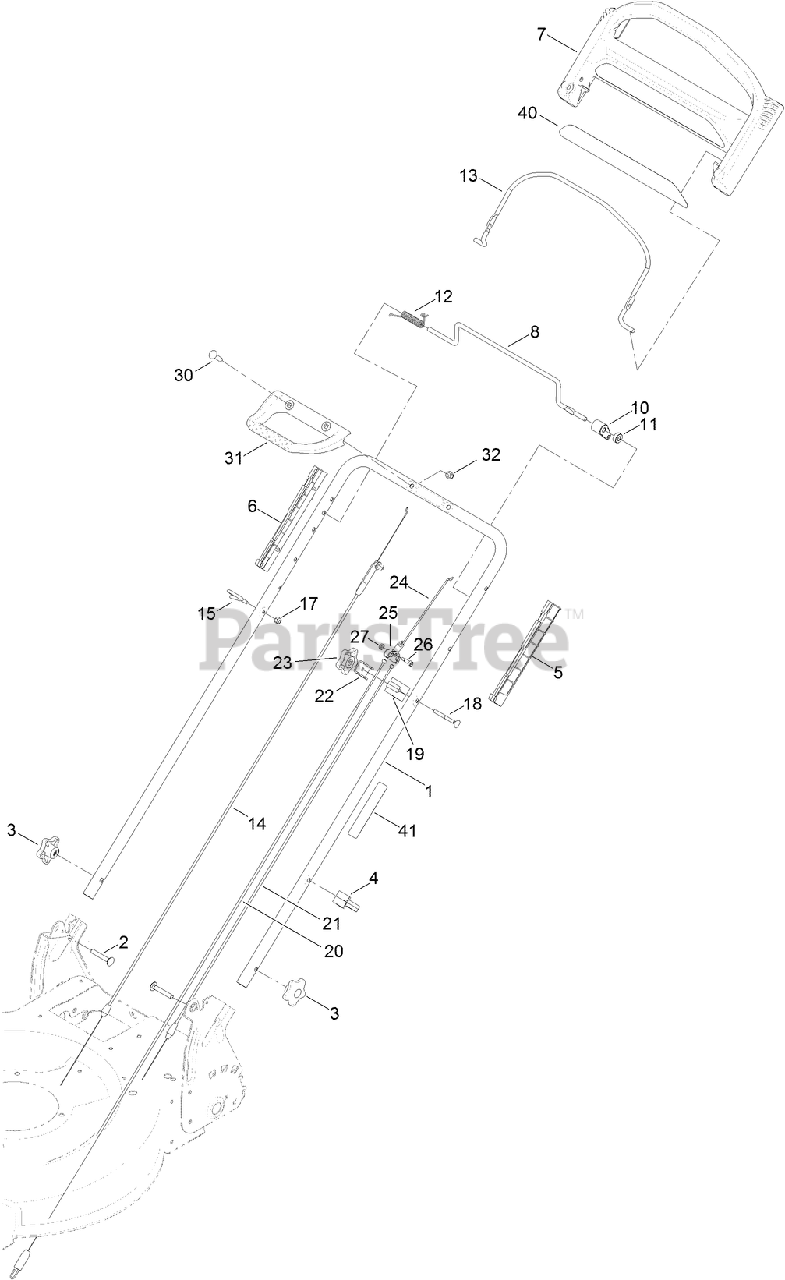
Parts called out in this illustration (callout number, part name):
2	BOLT-CARR
3	KNOB-HANDLE
4	GUIDE-CABLE
5	GUIDE-LH
6	GUIDE-RH
7	HANDLE-CONTROL
10	LEVER-TRACTION
11	SPACER
14	CABLE-BRAKE
15	GUIDE-ROPE
17	NUT-LOCK, NI
18	SCREW-HANDLE
19	MOUNT-CABLE, TRACTION
20	CABLE-TRACTION, FRONT
21	CABLE-TRACTION, REAR
23	KNOB-HANDLE, LOCKING
24	LINKAGE-EQUALIZER
25	YOKE-CABLE
26	SCREW-SHOULDER
27	NUT-LOCK, NI
30	BOLT-CARRIAGE
31	HANDLE-ASSIST, TRACTION
32	NUT-ACORN
